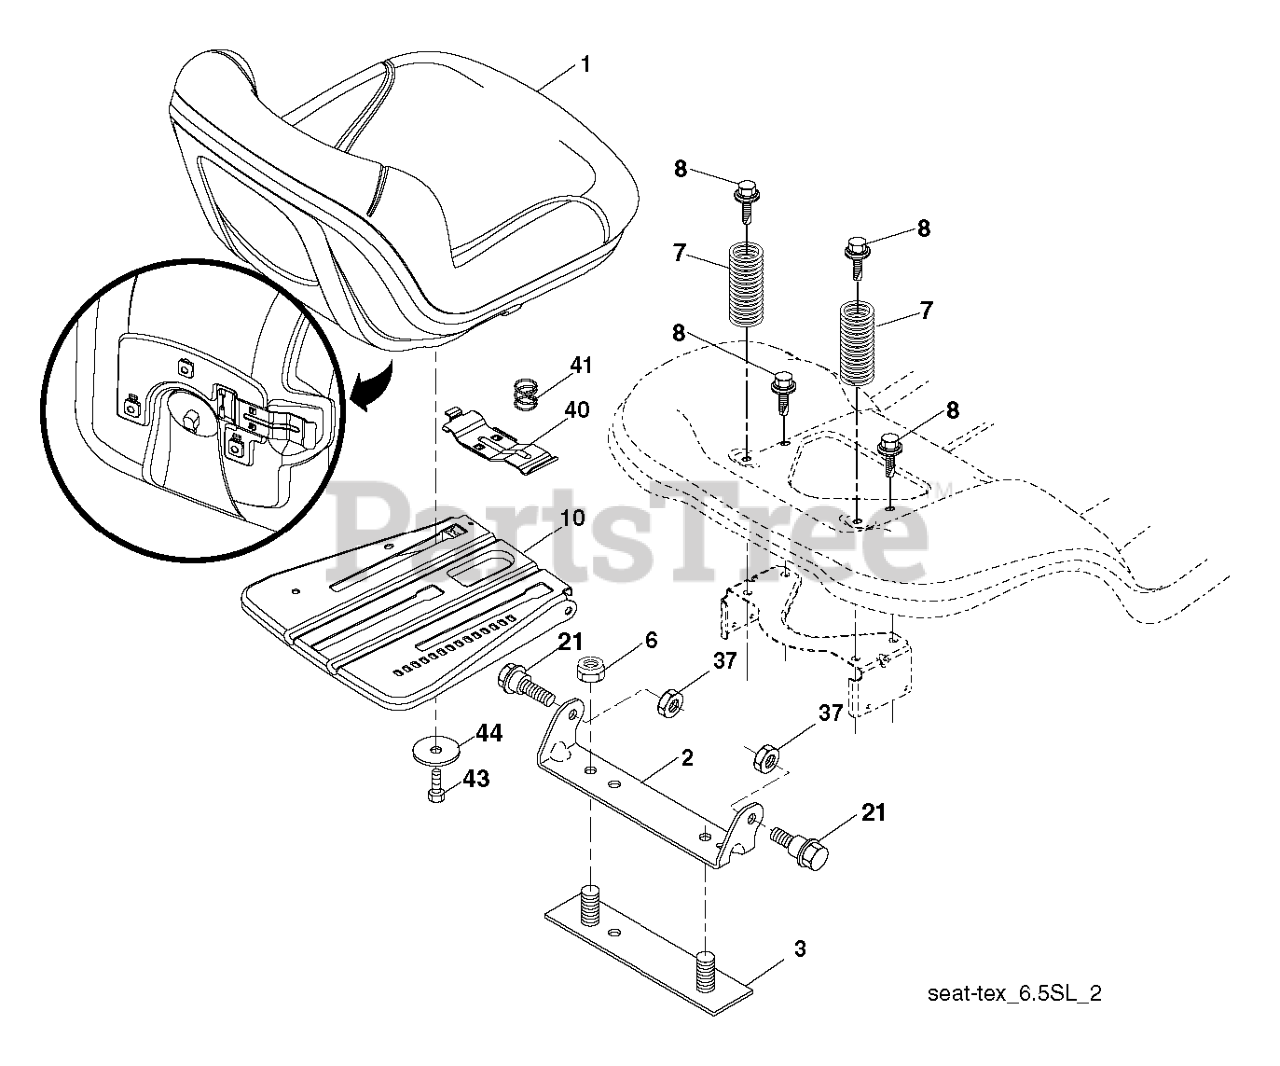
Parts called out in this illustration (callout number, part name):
1	SEAT.TH151.GREY.PREM.HUSQ.MI
2	BRKT.PIVOT.FENDER
3	STRAP
6	NUT
7	SPRING COMPRESSION
8	BOLT.5/16-18UNCX3/4 W/SEMS.BLK
10	PAN.ASM.SEAT.3PT
21	BOLT.SHOULDER.5/16-18
37	NUT.71038.31-18.HEX.NYLOCK
40	HANDLE.SLIDE.SEAT.TEX.GREY
41	SPRING.LATCH.SEAT.TEX
44	WASHER 13/32 X 2-3/8 X 12GA
